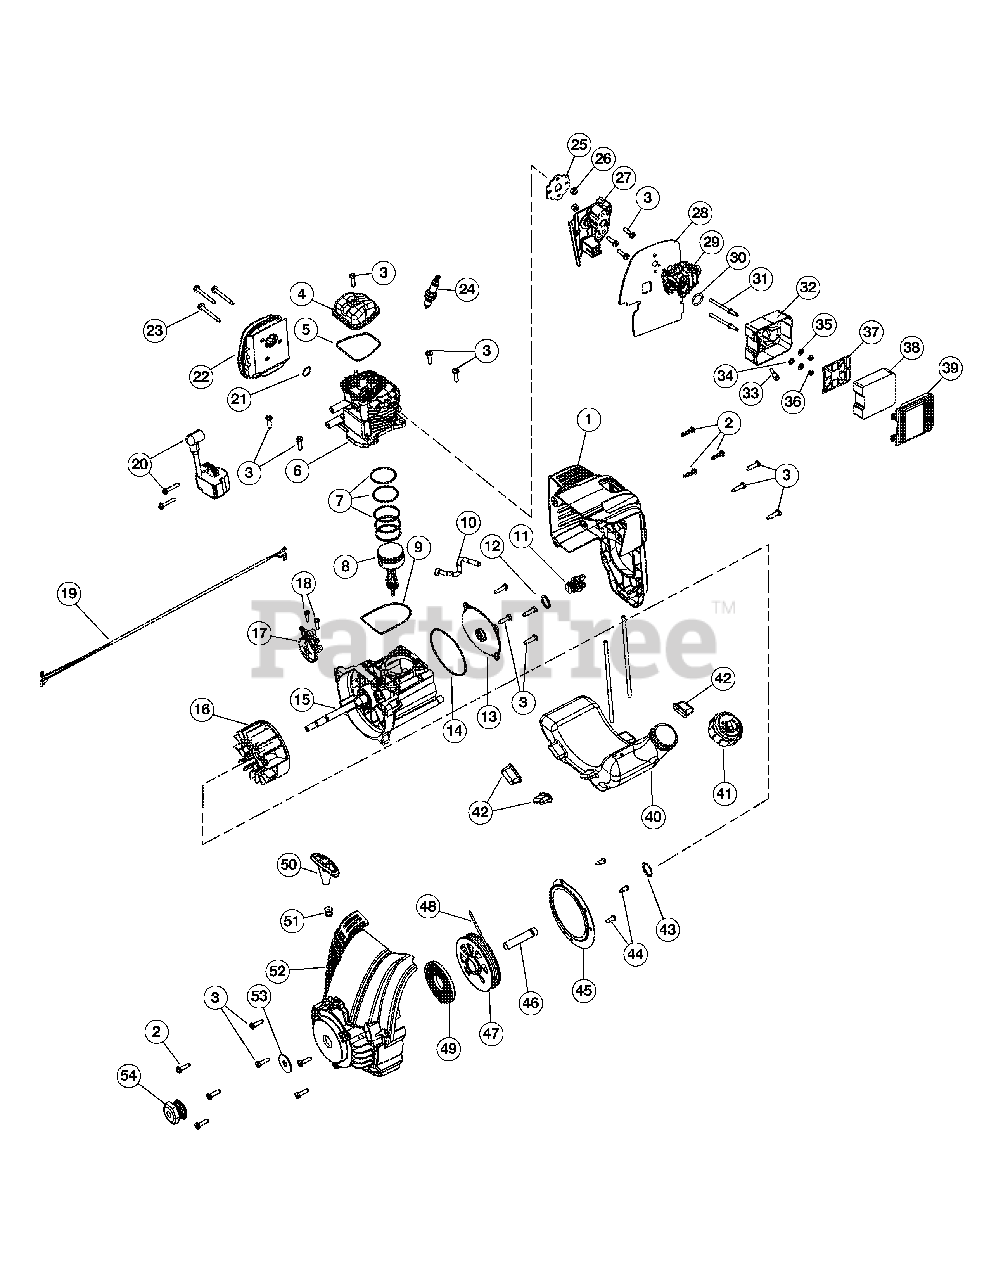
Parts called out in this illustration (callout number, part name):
1	Engine Cover Assembly
2	Cover Screw
3	Screw
4	Rocker Cover
5	Rocker Cover O-Ring
6	Cylinder Assembly
7	Piston Ring Assembly
8	Piston Assembly
9	Cylinder O-Ring
10	Breather Hose
11	Oil Plug
12	Oil Plug O-Ring
13	Crankcase Cover
14	Crankcase Cover O-ring
15	Crankcase Assembly
16	Flywheel Assembly
17	Cam Bracket Assembly
18	Cam Bracket Screw
19	Lead Wires
20	Module Assembly
21	Muffler Gasket
22	Muffler Assembly
23	Muffler Screw
24	Spark Plug
25	Insulator Gasket
26	Nut
27	Insulator
28	Carburetor Gasket
29	Carburetor w/Primer
30	O-Ring
31	Air Filter Mounting Screw
32	Air Cleaner Cover Assembly
33	Breather Tube
34	Grommet Washer
36	Nut
37	Air Filter Plate
38	Air Filter
39	Air Filter Cover
40	Fuel Tank Assembly w/Fuel Lines
41	Fuel Cap
42	Fuel Tank Pads
43	Push Nut
44	Pressure Plate Screw
45	Pressure Plate
46	Spacer
47	Starter Assembly
49	Recoil Spring
50	Pull Handle
51	Rope Guide
52	Starter Housing Assembly
53	Washer
54	Drive Shaft Pulley
